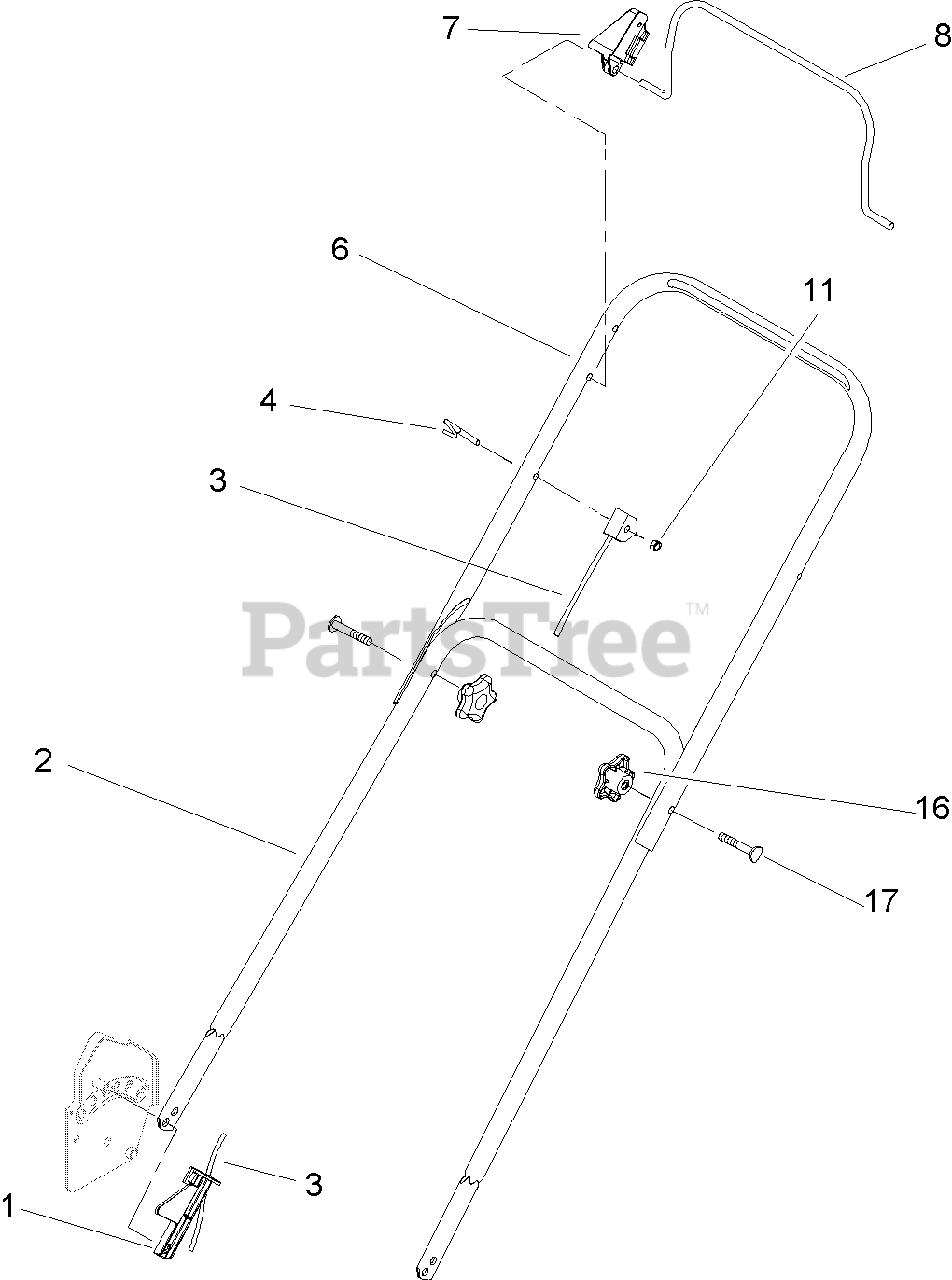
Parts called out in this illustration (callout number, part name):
1	GUARD-CABLE
2	HANDLE-LOWER
3	BRAKE CABLE ASM
4	GUIDE-ROPE
6	HANDLE-UPPER
7	STOP-PIVOT
8	BAIL-BRAKE
11	NUT-LOCK, NI
16	KNOB-HANDLE
